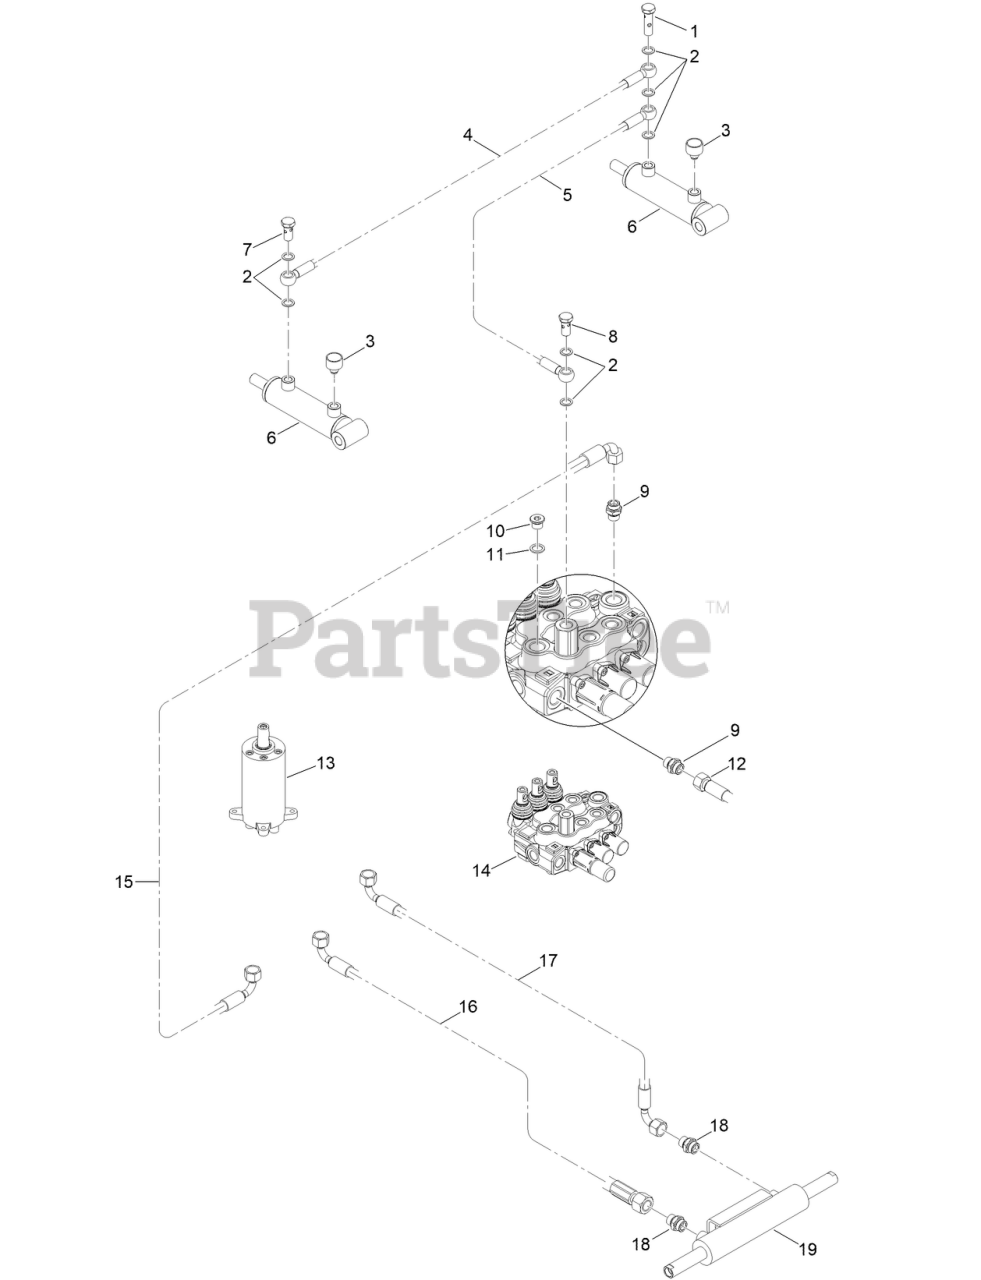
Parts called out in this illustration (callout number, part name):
2	WASHER
3	CAP-BREATHER
8	FITTING-ORIFICE
9	FITTING-NIPPLE
11	SEAL - 3/8in
13	STEERING VALVE
14	VALVE-LIFT
18	FITTING-NIPPLE
